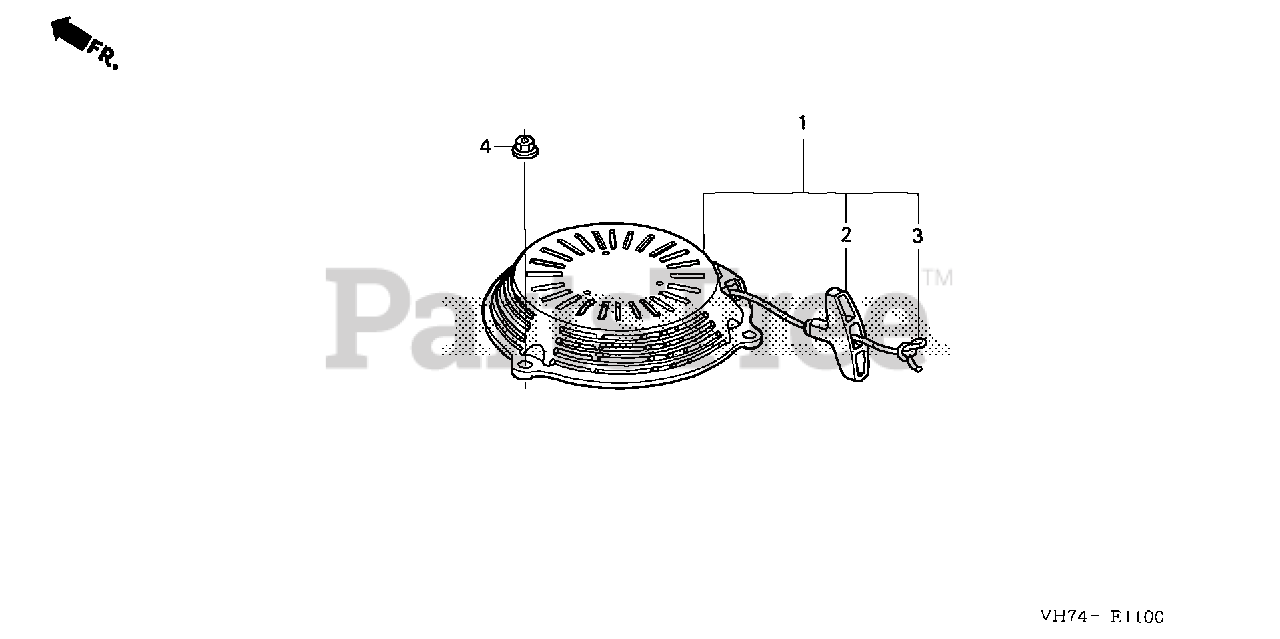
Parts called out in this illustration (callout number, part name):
1	STARTER ASSY., RECOIL *R280* (LONG ROPE) (POWER RED)
2	KNOB, RECOIL STARTER
3	ROPE, RECOIL STARTER (LONG TYPE)
4	NUT, FLANGE (6MM)
